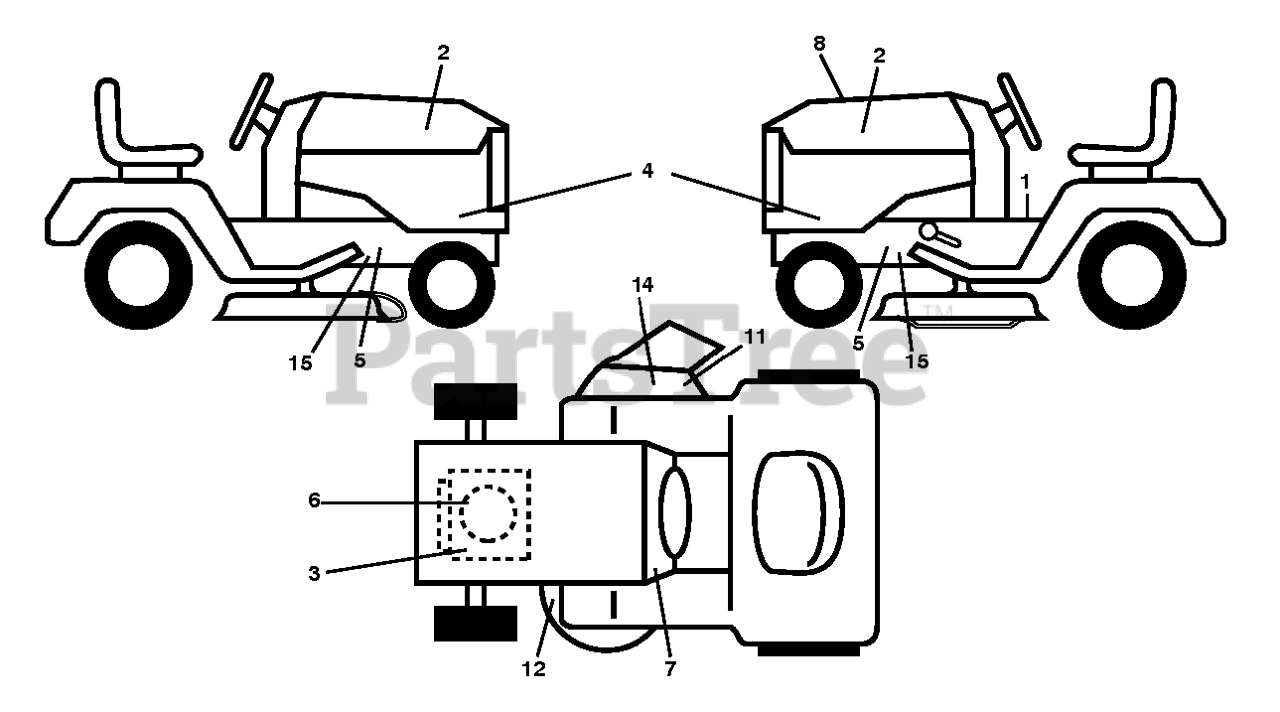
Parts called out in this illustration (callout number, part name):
1	DECAL TRACTOR SADDLE DECAL DEC
2	DECAL.BADGE.170MM.TEXTLOGO.
3	DECAL.ENGINE.WARNING
4	DECAL.SDPNL.HUSQLT.TS238
5	DECAL.CHASSIS.HOT.MUFFLER
6	DECAL.ENG.BS.500CC.ENDR.382273
7	DECAL.SNOWFLAKE.MS498.HUSQ
8	DECAL.RPL.BSM31.HS.TLW.97.K46
11	DECAL.DFLCTR.WARNNG.CTFNGR.SYM
12	DECAL.DECK.SCH.36,38,94.NONCR
14	DECAL, DECK DEFLECTOR, WARNING
15	DECAL.WARNING.SERVCE/FIRE
